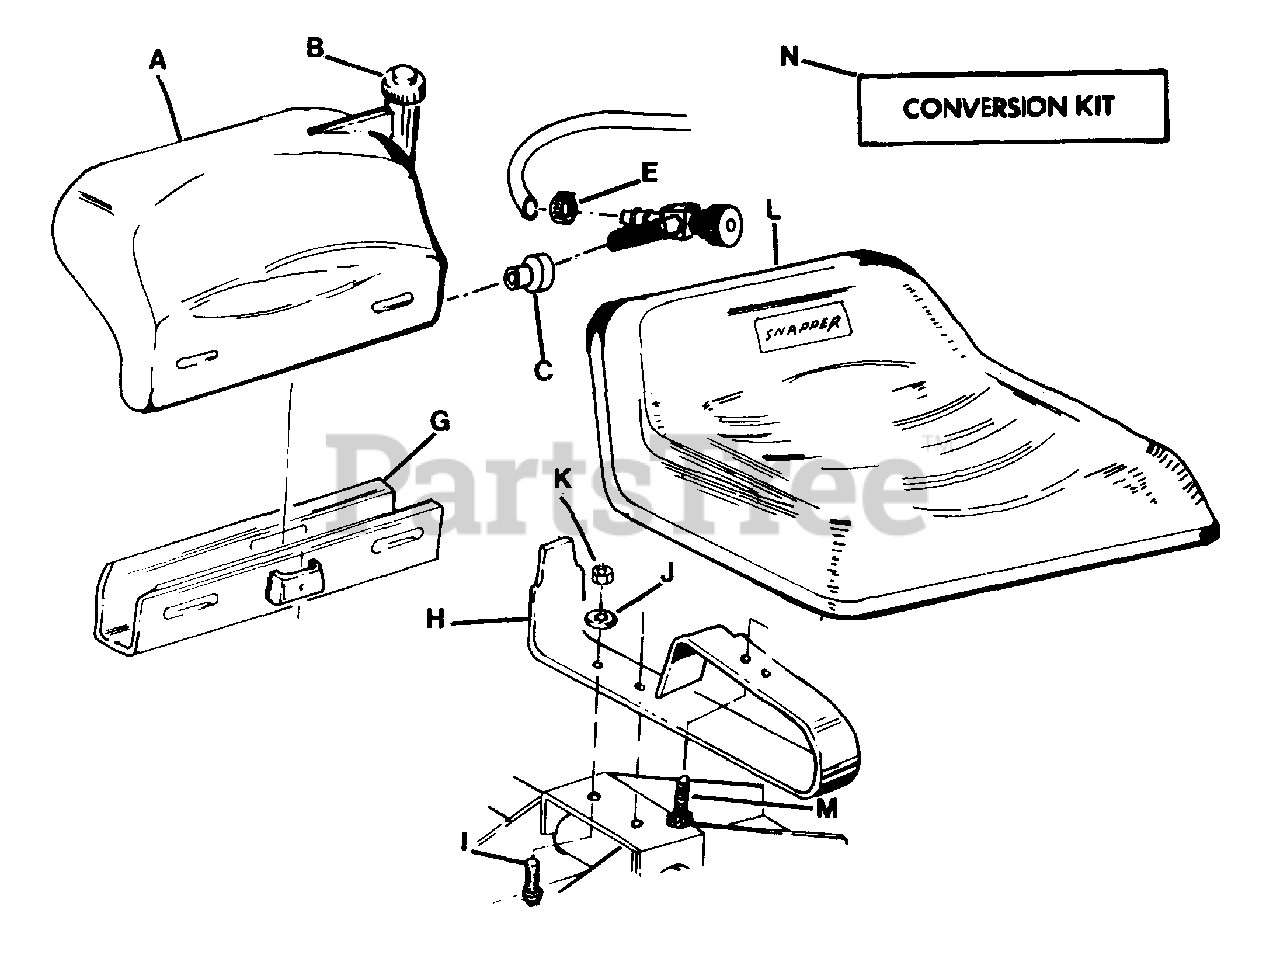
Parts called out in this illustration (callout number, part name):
A	TANK, FUEL
B	CAP, GAS TANK FILLER
C	GROMMET, FUEL VALVE
E	CLAMP, FUEL LINE
G	BRACKET, FUEL TANK
H	SPRING, OPERATORS SEAT
I	SCREW, HEX HEAD CAP 3/8-16 x 1
J	WASHER, 3/8 INTERNAL TOOTH LOCK
K	NUT, 3/8-16 HEX
L	SEAT, OPERATOR'S
M	SCREW, GRADE 5 CAP 1/2-13 x 7/8
N	KIT, GAS TANK
